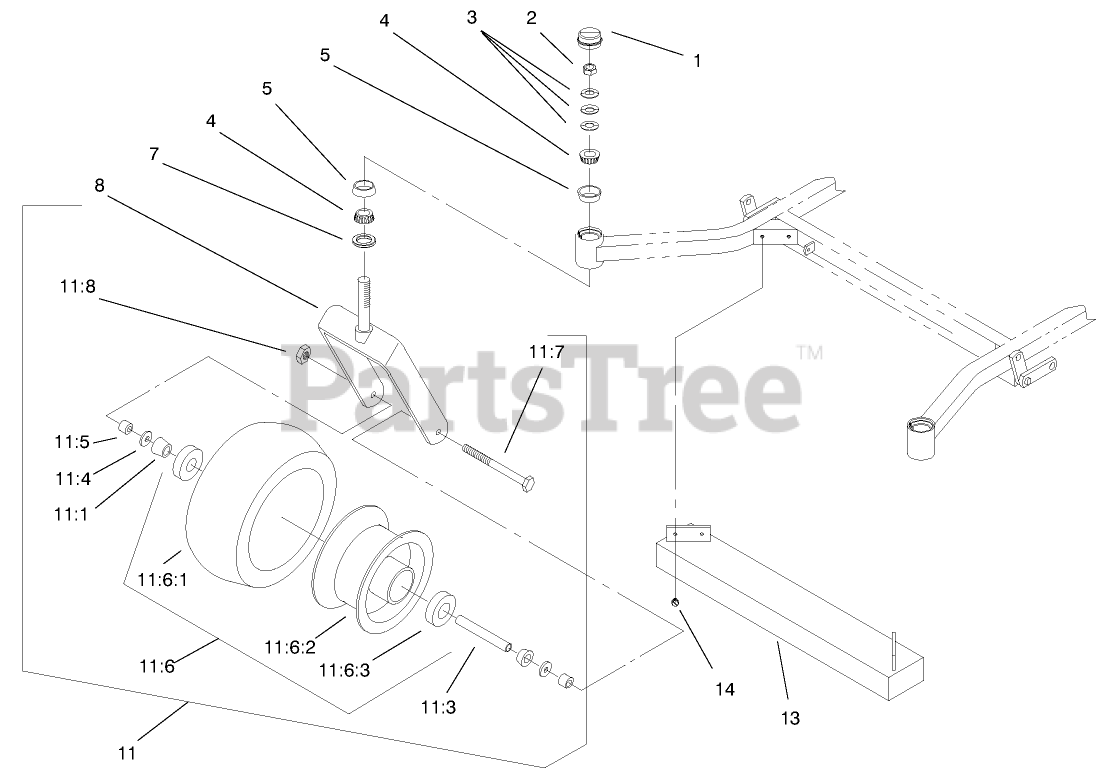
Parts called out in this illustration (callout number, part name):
1	Cap-Grease
2	LOCKNUT
3	Washer-Bellevue
4	BEARING-CONE, TAPERED
5	BEARING-CUP, TAPERED
7	Seal-Grease
8	Caster
11	Caster Wheel ASM
11:1	BEARING-CONE
11:3	Spacer
11:4	Seal-Bearing
11:5	Spacer-Bearing
11:6	Wheel & Tire ASM
11:6:1	Tire
11:6:2	Wheel
11:6:3	BEARING-ROLLER, CUP
11:7	SCREW-HH
11:8	NUT-LOCK, NI
13	Weight
14	SCREW-HWHTF
